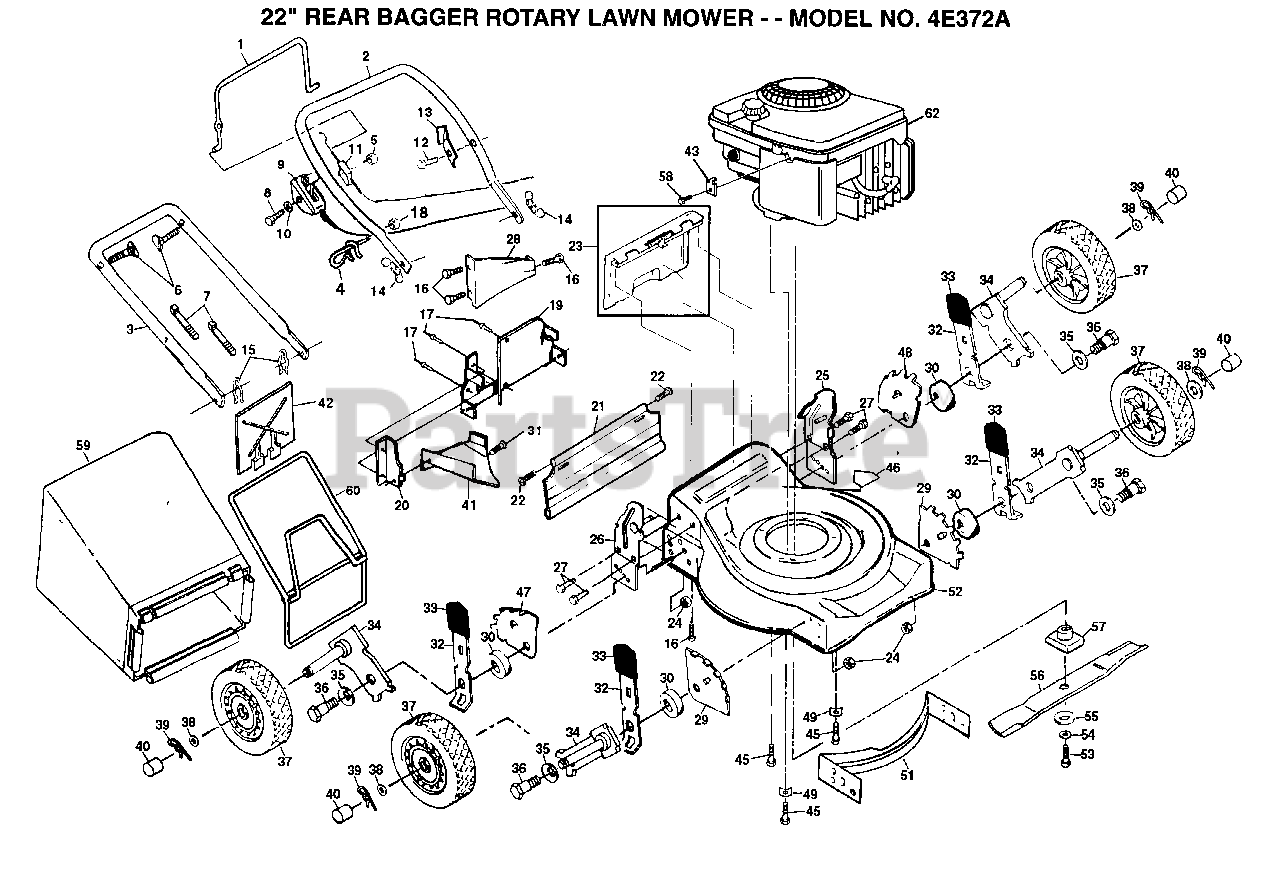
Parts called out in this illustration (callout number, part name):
1	CONTROL BAR
4	ROPE GUIDE
6	BOLT.HANDLE.LM
9	CNTL.THROT.47.5
10	WASHER PM
11	"CABLE,ENG ZONE CO"
12	TAPPING SCREW
13	"BRKT,UPSTOP"
14	"NUT,WING PM"
15	HAIRPIN COTTER
16	SCREW
17	BLIND RIVET
18	NUT
19	PLATE.BACK
22	HINGE SCREW
24	LOCKNUT PM
27	SCREW
28	REAR BAFFLE
31	SCREW PM
32	SPRING SELECTOR
33	KNOB PM
34	AXLE ARM
35	"WASHER, BELLEVIL."
38	WASHER
39	RETAINER CLIP PM
40	HUB CAP
41	DISCHARGE BAFFLE
42	MULCHER PLATE
43	CABLE CLAMP
45	SCREW
46	DECAL HYT
52	KIT.HSG.22RD.PUSH
53	SCREW
54	LOCKWASHER
55	"WASHER,HARDEN"
58	SCREW PM
59	GRASS BAG
60	CATCHER FRAME
